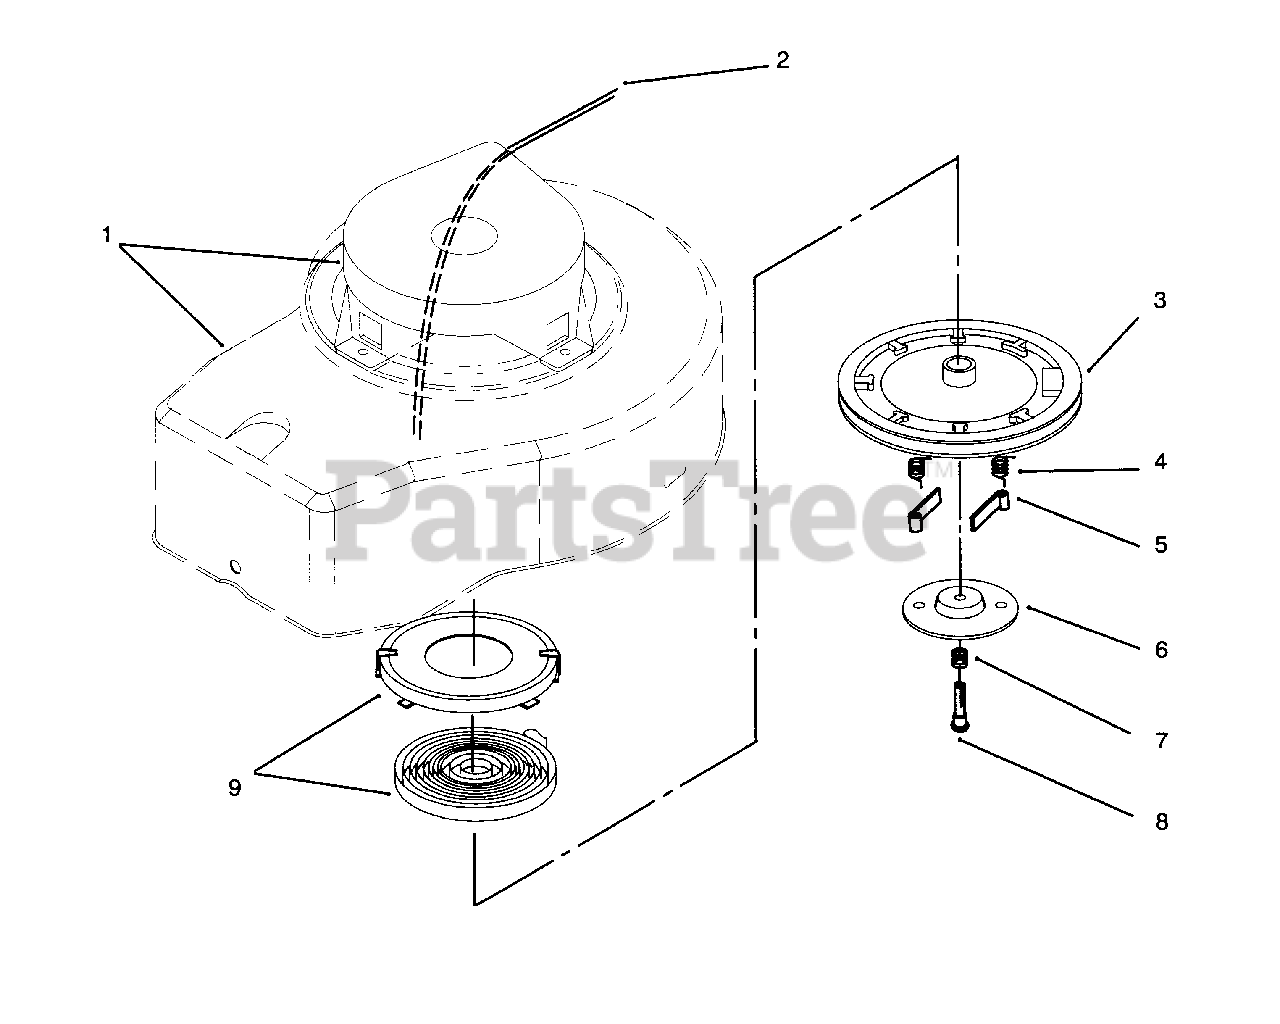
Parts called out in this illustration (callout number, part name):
1	Housing Assembly
2	Rope-Starter
3	Pulley Assembly
4	Spring-Dog
6	Retainer
9	Spring Keeper Assembly
